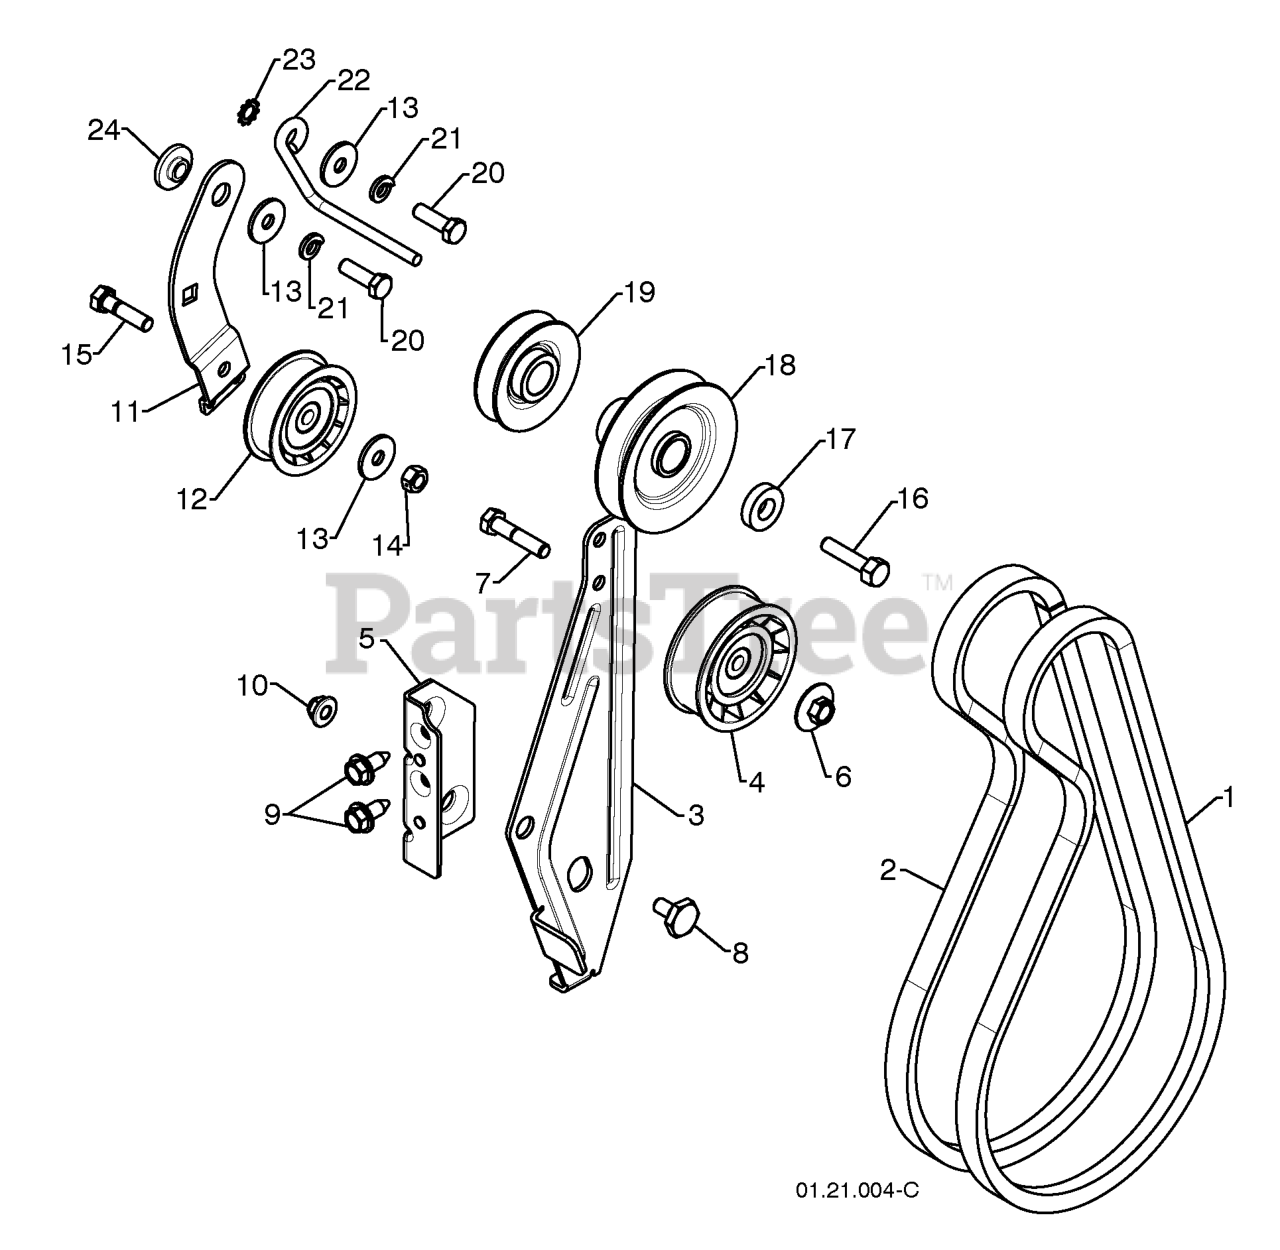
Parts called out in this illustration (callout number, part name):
1	VBELT; IMPELLER_39.09
2	V-BELT TRACTION 34.25
3	ARM.IDLER.BRAKE
4	PULLEY.IDLER.W/SPACER.
5	RP BRACKET.IDLER
6	NUT.FLANGE.HEX.5/16X18.BLACK
7	HEX BOLT
8	BOLT.SHOULDER.1/2X12
9	BOLT.HEX.HD.WASHER.5/16-18X.75
10	NUT.LOCK.5/16-18
11	ARM, IDLER
12	PULLEY.W/SPACER.2.25
13	STEEL WASHER
14	NUT.71038.31-18.HEX.NYLOCK
15	BOLT.5/16-18X1-1/4 FULL.THREAD
16	SCREW, HEX HD 3/8-24 X 1-3/8
17	WASHER, FLAT 3/8
18	PULLEY.ENG.IMPELLER.SNOW
19	PULLEY.ENG.TRACTION
21	WASHER.LOCK.HVY.HLCL.SPR.5/16
22	BELT.GUIDE.RH
23	WASHER EXT TOOTH LOCK 5/16
24	RP BUSHING, IDLER PIVOT
